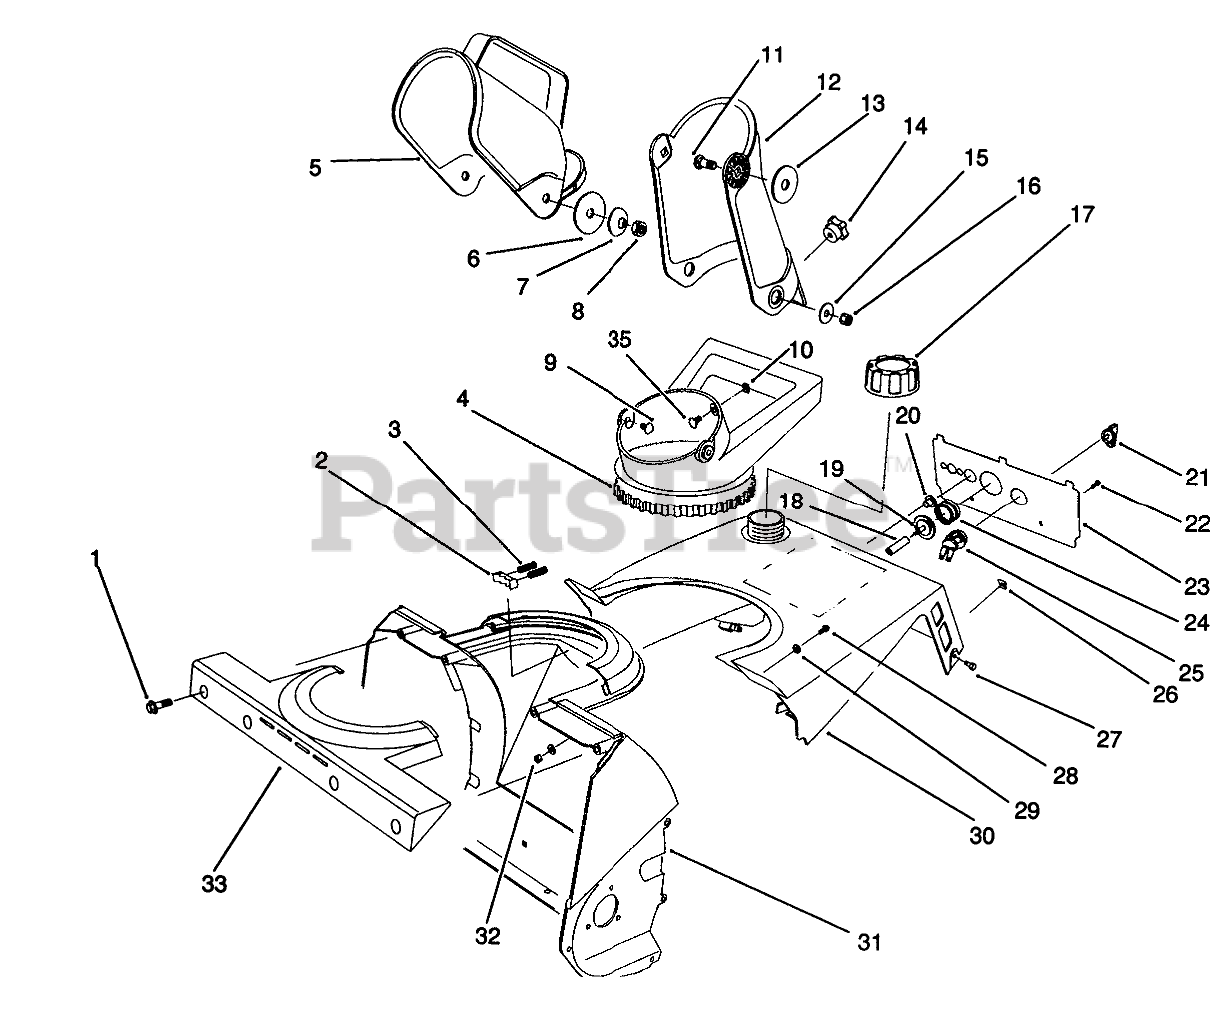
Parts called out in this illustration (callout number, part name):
1	SCREW-PLASTIC
2	DETENT-CHUTE
3	SPRING-COMPRESSION
3	Shroud-Upper (Model 38175)
4	HANDLE-CHUTE
5	DEFLECTOR-CHUTE
6	WASHER-FLAT
7	WASHER-BELLEVILLE
8	NUT-LOCK, NI
9	SCREW-HH
10	PUSHNUT-RETAINER, BOLT
11	BOLT-CARR
12	Chute
13	Washer-Rubber
14	KNOB-CHUTE
15	WASHER-FLAT
16	NUT-LOCK, NI
17	CAP-FUEL ASM
18	HOSE-PRIMER
19	BODY-PRIMER
20	GUIDE-ROPE, STARTER
21	KEY-IGNITION
22	SCREW-SHWH, THREAD FORMING
23	CNTRL PNL/SILK SCRN
24	BULB-PRIMER
25	SWITCH
27	SCREW-THREAD FORMING
28	SCREW-PPH
29	WASHER-FLAT
30	Shroud-Upper
31	HOUSING
32	NUT-LOCK, NI
33	RETAINER-CHUTE
34	DECAL - POWERLITE REC.
35	SCREW-CARR
